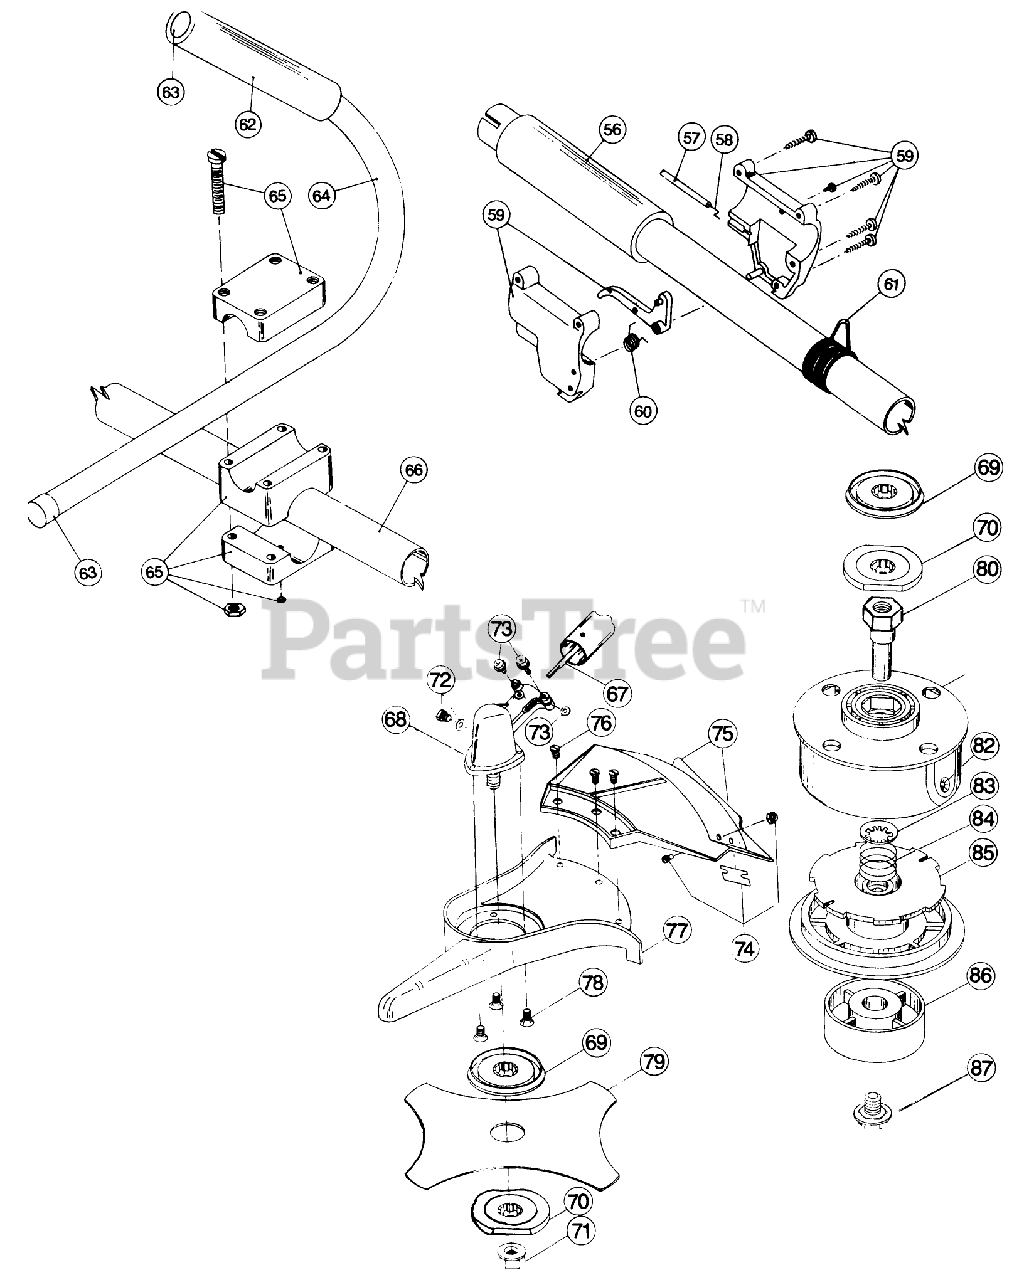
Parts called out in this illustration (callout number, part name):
58	THROTTLE CABLE WIRE
60	THROTTLE TRIGGER SPRING
62	HANDLE NITRILE GRIP
63	TUBE CLOSURE
65	HANDLE BRACKET ASM
66	DRIVE SHAFT HSG ASM
68	GEAR BOX ASM
74	BLADE ASM
75	GUARD & BLADE ASM
76	GUARD MNTG SCREW ASM
77	GUARD MOUNTING SCREWS
81	OUTER SPOOL EYELET ASM
82	EYELET
83	RETAINER
84	SPRING
88	STRAP SHOULDER ACC
